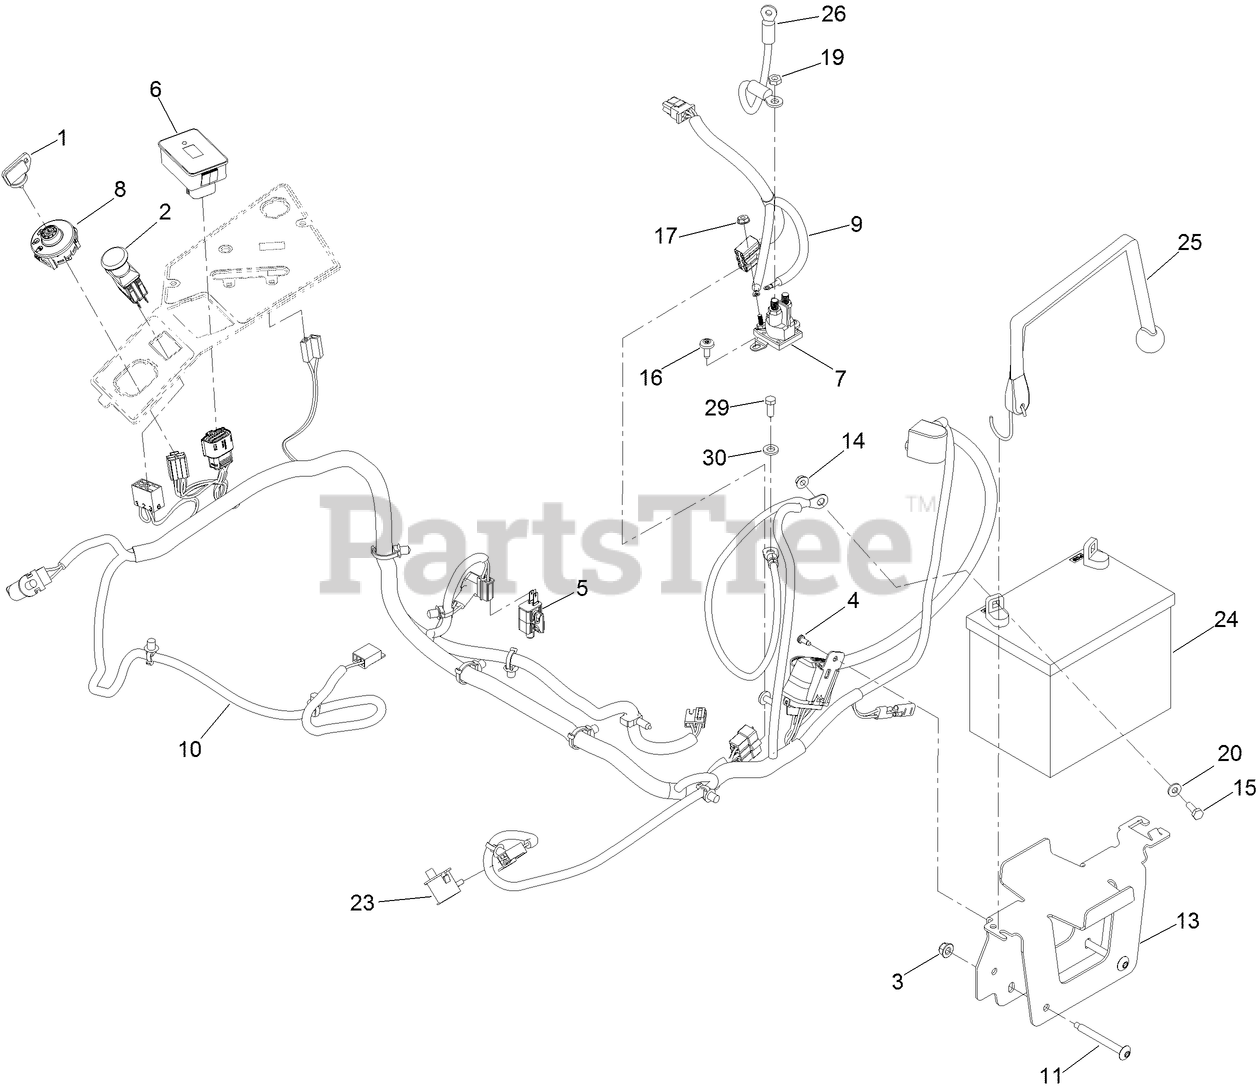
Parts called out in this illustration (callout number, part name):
1	KEY-IGNITION
2	SWITCH-PTO
3	NUT-HF, NI
4	SCREW-FORMING, THREAD
5	SWITCH
6	MODULE ASM
7	SOLENOID
8	SWITCH-IGNITION
9	ADAPTER-HARNESS, WIRE
10	HARNESS-WIRE
11	SCREW-TORX
13	TRAY-BATTERY
14	NUT-HF
15	SCREW-HH
16	SCREW-TORX
17	NUT-KEPS
19	NUT-JAM
20	WASHER-FLAT
23	SWITCH-BAIL
24	BATTERY
25	STRAP-BUNGEE
26	CABLE-BATTERY, POSITIVE
29	SCREW-HH
30	WASHER-PLAIN
